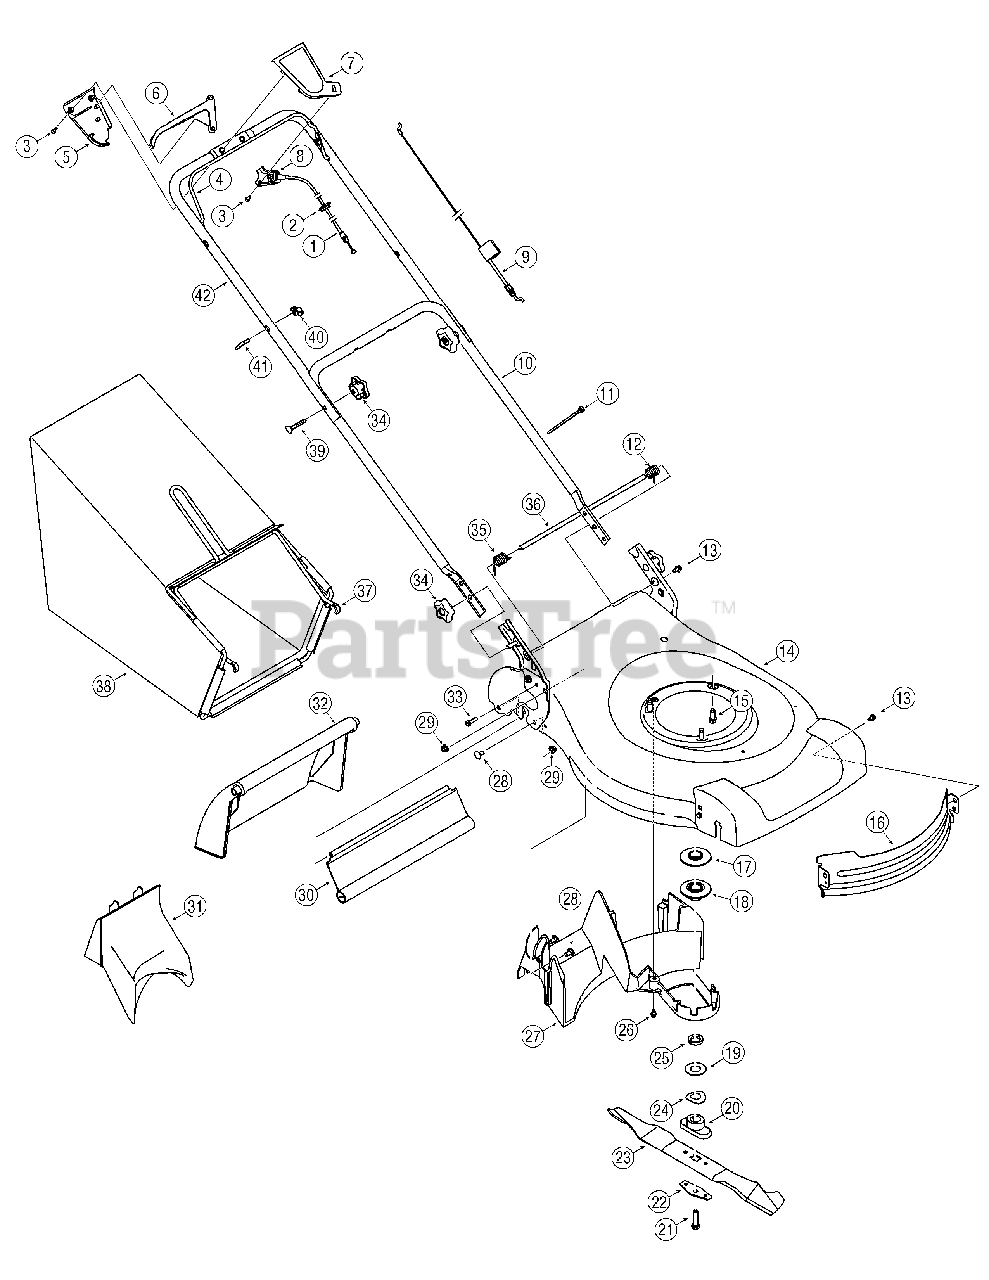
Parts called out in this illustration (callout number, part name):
1	Drive Cable
2	Rubber Grommet
3	Screw, #10-16 x .750
5	Lower Control Cover
6	Drive Control Lever
7	Upper Control Cover
8	Mounting Cap
9	Control Cable
11	Cable Tie
12	Torsion Spring, LH
13	TT Screw, 1/4-20 x .500
16	Deck Baffle
17	Upper Engine Pulley
18	Lower Engine Pulley
19	Flat Washer, .885 x 1.850 x .060
20	Blade Adapter
21	Screw, 3/8-24 x 1.50
22	Blade Bell Support
23	21" Mulching Blade
24	Spring Washer, .890 x 1.70 x .048
25	Sleeve Spacer
26	TT Screw, 1/4-20 x .375
27	Deck Baffle
28	Carriage Bolt, 5/16-18 x .62
29	Flange Lock Nut, 5/16-18
30	Trail shield
31	Mulch Plug
32	Rear Door
33	Screw, 1/4-15 x 1.00
34	Star Knob
35	Torsion Spring, RH
36	Door Pivot Rod
39	Carriage Bolt, 5/16-18 x 2.00
40	Wing Nut
41	Eye Bolt
